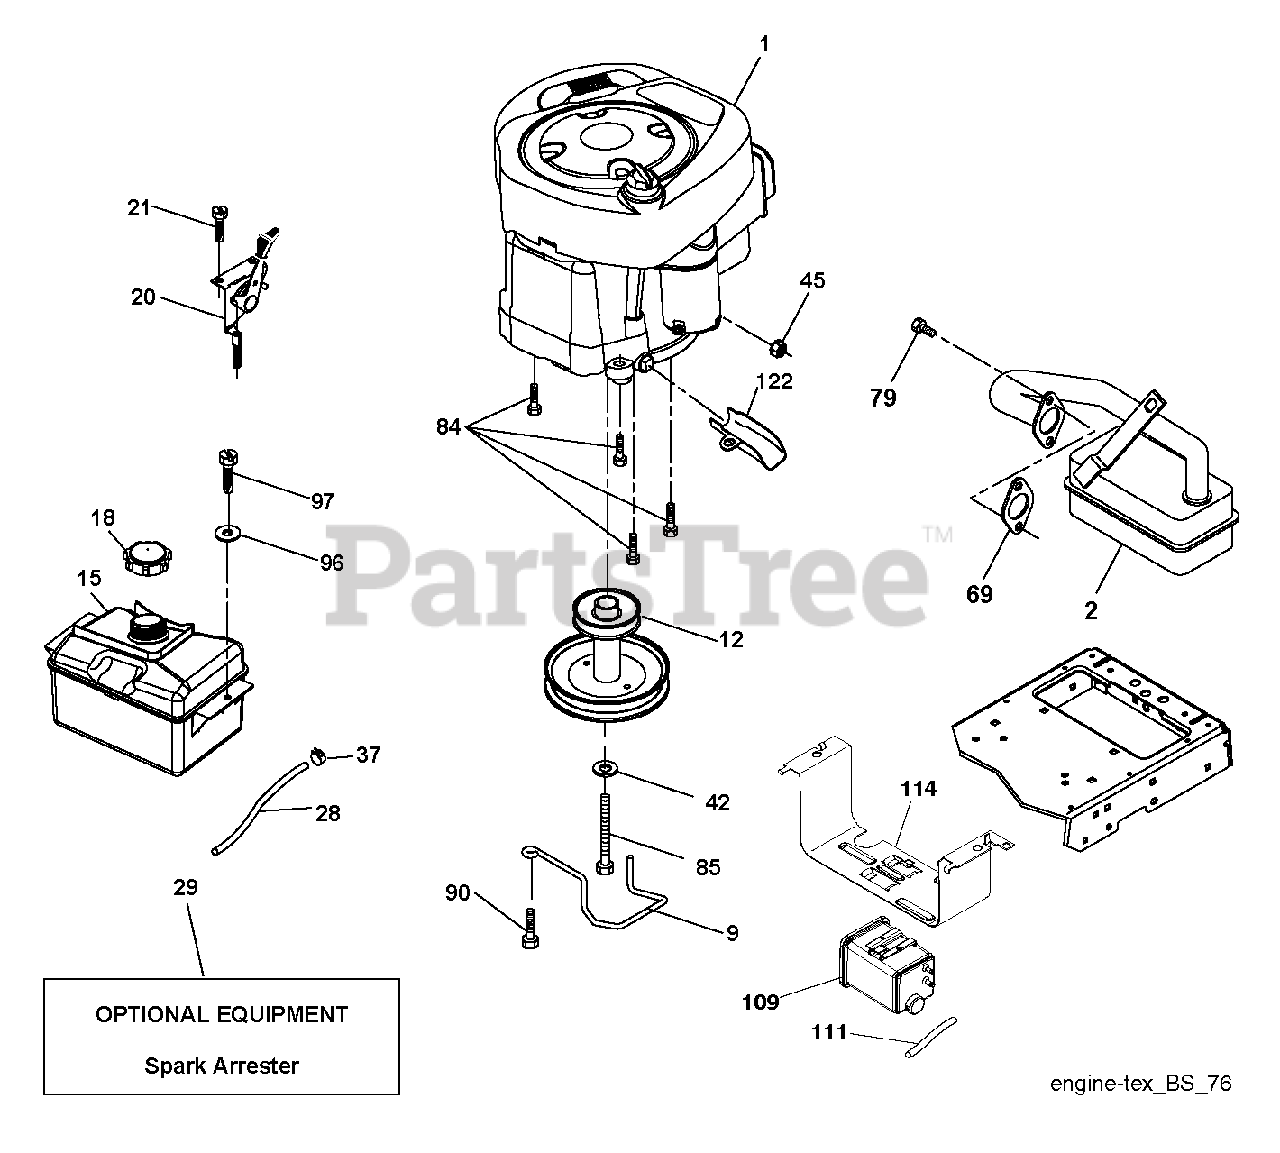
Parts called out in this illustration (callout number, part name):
2	MUFFLER.LT.BRIGGS.14HP.IC/OHV
9	KEEPER.BELT.ENGINE.3.25
12	PULLEY.ENGINE.5.0.PD
15	TANK ASM.FRT.CRB.1.5GA.E10.SVC
18	CAP ASM.FUEL.2.25"FRT.CARB
20	CONTROL.THROTTLE/CHOKE.BLACK
21	SCREW.#10 X 0.750.BOS (2 2)
28	LINE.FUEL.20"FRONT.EMI
29	SPARK ARRESTOR KIT
37	HOSE CLAMP
42	LOCKWASHER
45	NUT
79	SCREW.SOCKET HD.5/16-1
84	SCREW.3/8-16
85	BOLT HEX 7/16-20X4-1/4"
90	SCREW 3/8-16X1
97	SCREW HEXWSHR 1/4-20X3/4
109	CANNISTER, CARBON
111	RP PURGE LINE
122	EXTENSION DRAIN OIL
